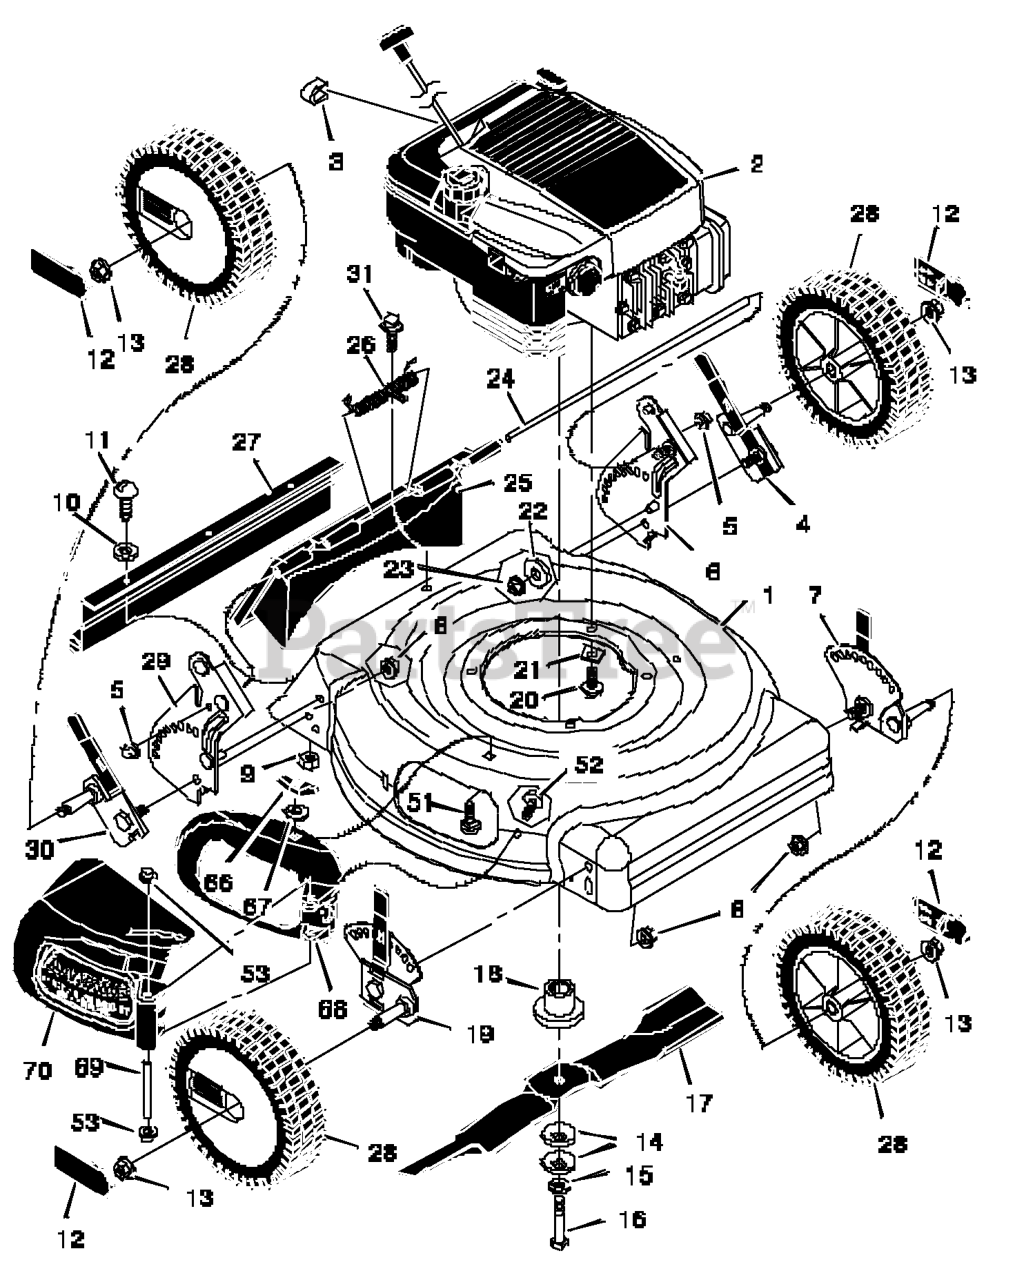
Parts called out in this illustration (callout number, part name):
1	Housing
2	Engine *
3	Stop, Rope (Recoil - Start)
4	Adjuster, Left Height
5	Nut, Push
6	Bracket, Left Handle
7	Adjuster, Left Front Height
8	Nut, Flange
9	Nut, Hex
12	Hub Cap
13	Nut, Flange
14	Washer, Belleville
18	Adapter, Blade
20	Bolt, Engine
21	Support, Engine
22	Washer
23	Nut, Flange
24	Rod, Pivot
25	Door, Rear
27	Guard, Rear
28	Wheel (Dark Gray)
29	Bracket, Right Handle
30	Adjuster, Right Height
51	Bolt, Carriage
53	Push On Cap
66	Wingnut
67	Retainer, Push
69	Pin, Pivot
70	Deflector, Chute
